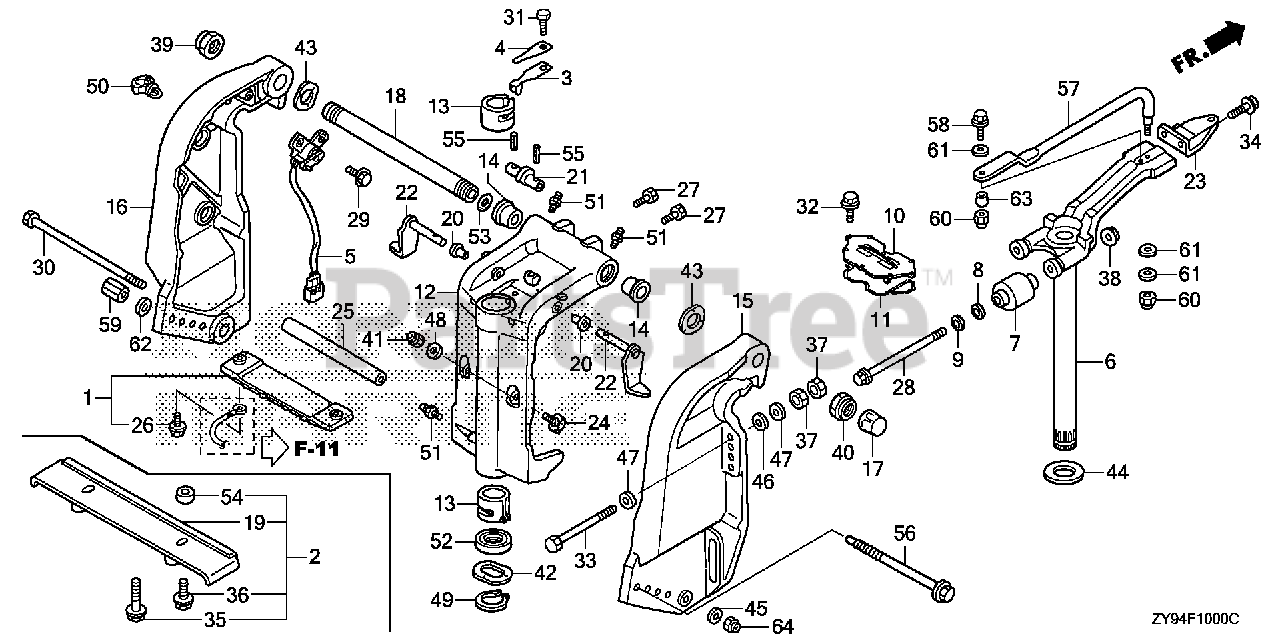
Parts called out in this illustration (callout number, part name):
1	METAL KIT, ANODE
2	PLATE KIT, SPLASH
3	SPRING, CLICK
4	SPRING, CLICK ASSIST
5	SENSOR ASSY., TRIM ANGLE
6	FRAME, MOUNTING
7	MOUNT, RUBBER (UPPER)
8	RUBBER, MOUNT STOPPER (UPPER)
9	STOPPER, MOUNT (UPPER)
10	COVER, MOUNT (UPPER)
11	SEAL, MOUNT COVER (UPPER)
12	CASE, SWIVEL *NH282MU* (OYSTER SILVER METALLIC-U)
13	LINER, SWIVEL CASE
14	BUSH, SWIVEL CASE
15	BRACKET, R. STERN *NH282MU* (OYSTER SILVER METALLIC-U)
16	BRACKET, L. STERN *NH282MU* (OYSTER SILVER METALLIC-U)
17	CAP, TILTING BOLT
18	SHAFT, TILTING
19	PLATE, SPLASH
20	BUSH, TILT ARM
21	BRACKET, TILTING
22	STOPPER, TILT
23	PLATE, STEERING
24	RECEIVER, THRUST
25	COLLAR, CYLINDER (LOWER)
26	BOLT, FLANGE (6X23)
27	BOLT (1/4-28UNF)
28	BOLT, HEX. (12X186)
29	BOLT, FLANGE (6X20)
30	BOLT, HEX. (10X235)
31	BOLT, HEX. (6X14)
32	BOLT, FLANGE (8X25)
33	BOLT, HEX. (12X119)
34	BOLT, FLANGE (10X25)
35	BOLT, FLANGE (6X25) (SUS-D)
36	BOLT, FLANGE (6X16) (SUS)
37	NUT, HEX. (12MM)
38	NUT, FLANGE (12MM)
39	NUT, SELF-LOCK (7/8-14UNF)
40	NUT, SELF-LOCK (25X2.0)
41	NUT, SELF-LOCK (10MM)
42	WASHER, WAVE (40MM)
43	WASHER, WAVE (26MM)
44	WASHER, THRUST (34MM)
45	WASHER, PLAIN (10MM)
46	WASHER, PLAIN (12MM)
47	WASHER, PLAIN (12MM)
48	WASHER, PLAIN (10MM)
49	CIRCLIP (OUTER) (39MM)
50	CLIP, WIRE HARNESS
51	NIPPLE, GREASE
52	OIL SEAL (39.5X52X6) (ARAI)
53	O-RING (15.54X2.62)
54	COLLAR, SPLASH PLATE
55	PIN, SPRING (2.5X20)
56	ROD, ADJUSTING
57	ROD, STEERING
58	BOLT (3/8-24UNF)
59	NUT, ADJUSTER ROD
60	NUT, SELF-LOCK (3/8-24UNF)
61	WASHER (10MM)
62	WASHER, PLAIN (12MM)
63	COLLAR, STEERING ROD
64	NUT, SELF-LOCK (10MM)
